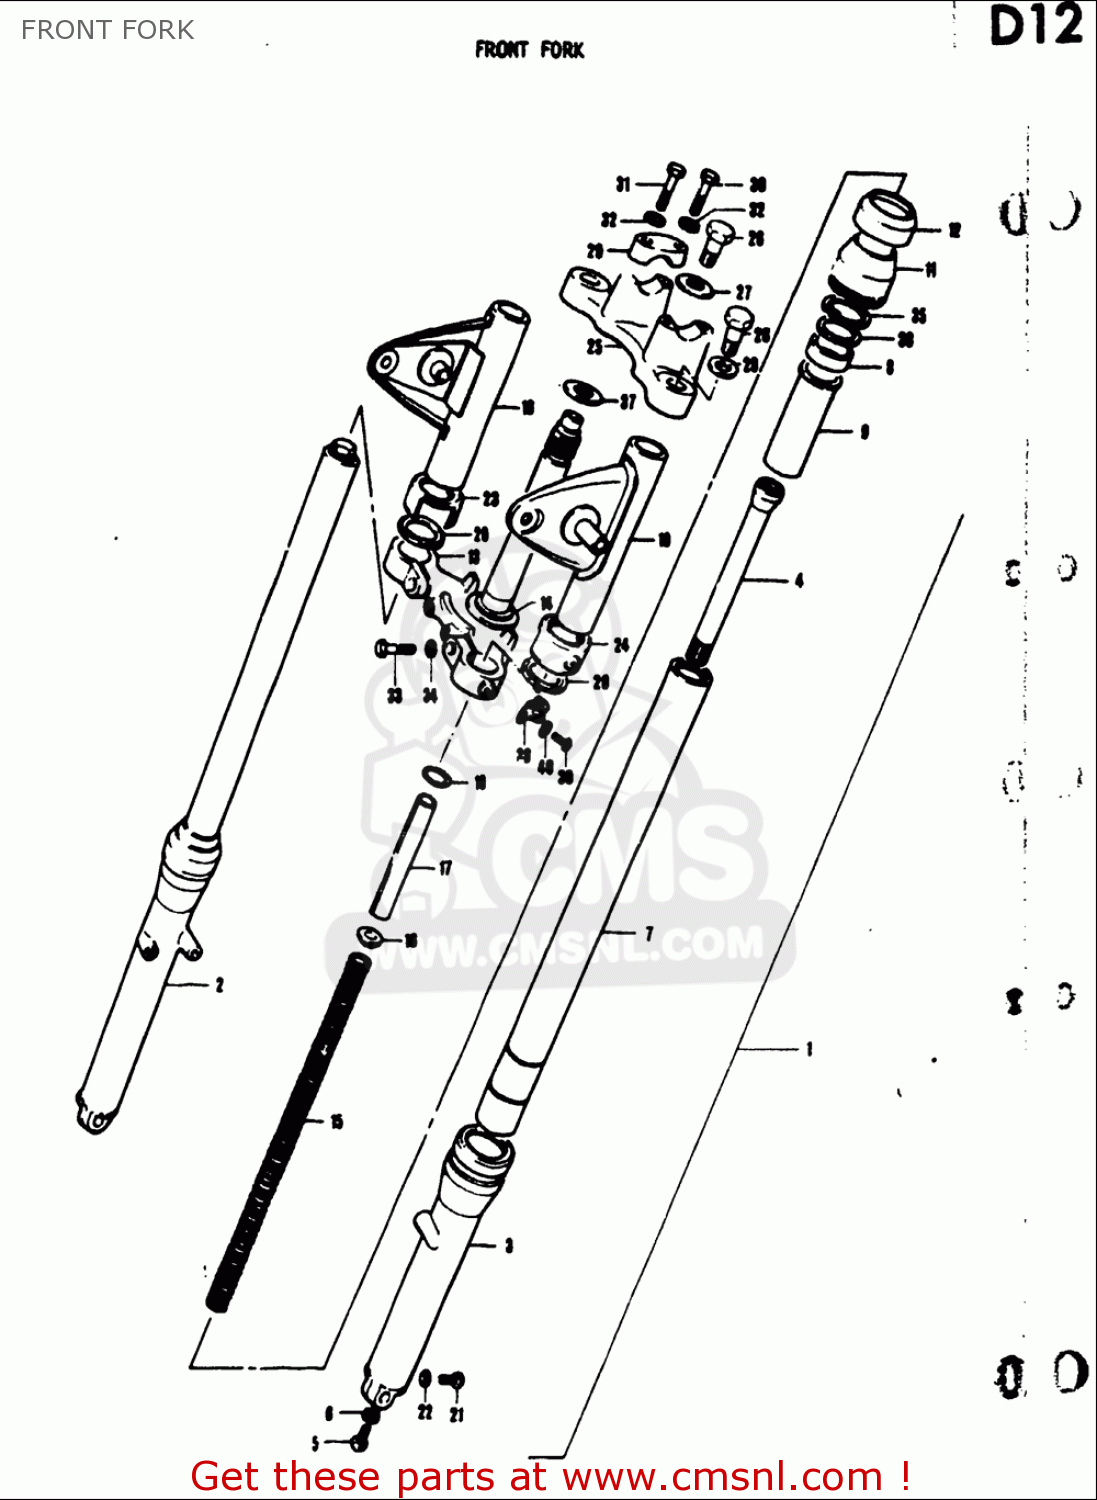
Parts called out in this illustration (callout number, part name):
5	SCREW
7	TUBE,FORK,INNER
8	SEAL,OIL
9	GUIDE,FRONT FORK TUBE
10	O RING
11	SEAL,DUST
14	RACE,STEERING OUTER LWR
21	SCREW
22	GASKET,DRAIN,PLUG (NAS)
26	BOLT,FR FORK(10X33)
27	WASHER
30	BOLT
32	WASHER,LOCK
34	WASHER,LOCK
35	CIRCLIP
36	RING,FORK BACK UP
38	CLIP,BRAKE CABLE
39	SCREW
40	WASHER,LOCK
